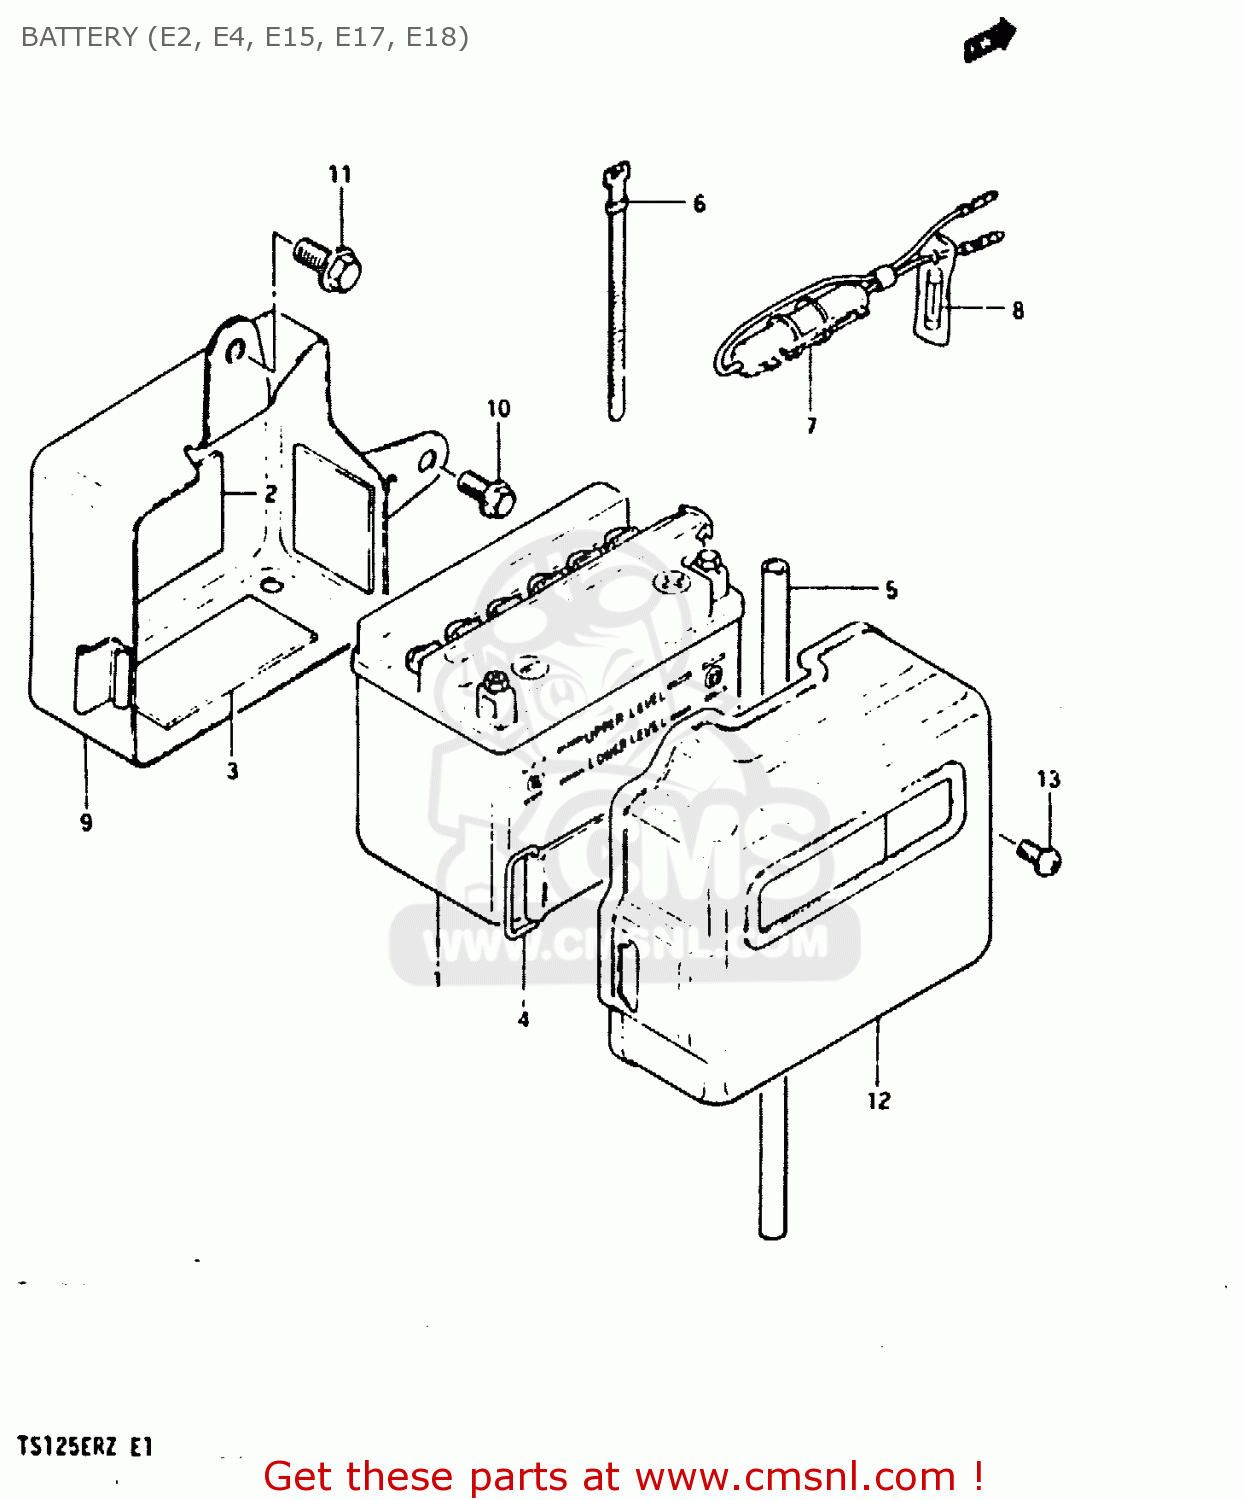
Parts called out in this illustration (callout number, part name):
1	BATTERY ASSY(YB4L-B,12V4.2AH)
2	PROTECTOR,BATTERY
3	PROTECTOR(20X90)X4
4	BAND
5	HOSE,BATTERY EXHAUST
6	CLAMP(L:120)
7	BOX ASSEMBLY,FUSE
8	FUSE(10A)
9	HOLDER,BATTERY
10	BOLT
11	BOLT
12	COVER,BATTERY
13	SCREW
